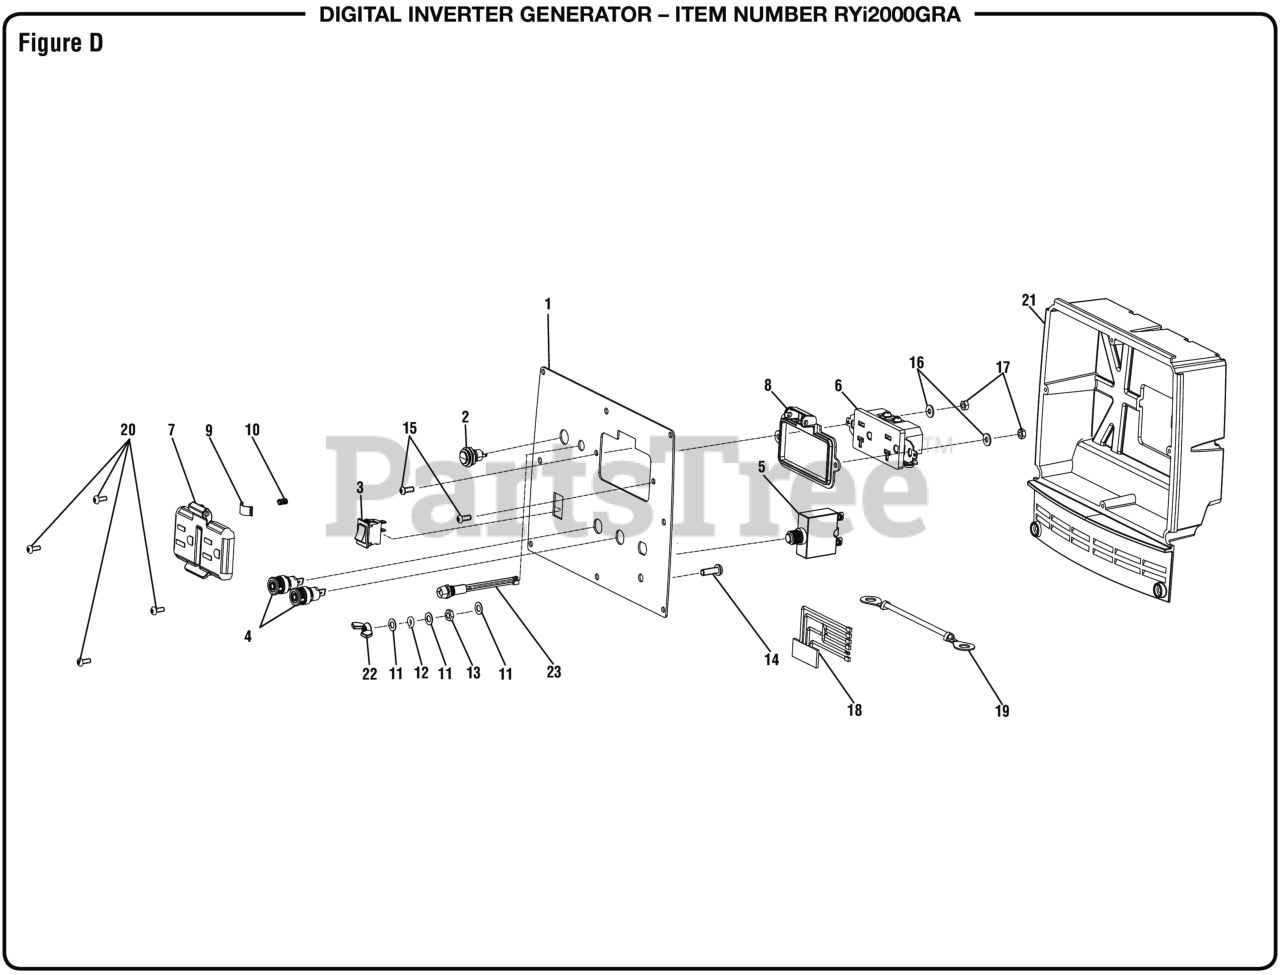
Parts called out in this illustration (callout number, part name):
1	Front Cover
2	Reset Button
3	Auto Idle Switch
4	Connector (Black)
5	Circuit Breaker (20 Amp, 125 Volt)
6	120 Volt Duplex Receptacle (BM903611)
7	Receptacle Cover (Front)
8	Fixed Outlet Cover
10	Governor Damping Spring
11	Flat Washer (OD10 x ID5.3 x 0.5t)
12	Lock Washer (OD9 x ID5 x 1.3t)
13	Hex Nut (M5)
14	Screw (M5 x 16 mm, Phillips Pan Hd.)
15	Bolt (M4 x 10 mm, T15 Torx Drive Hd.)
16	Flat Washer (OD10 x 42 x 1t)
17	Flange Nut (M4)
18	Internal Wire Assembly
19	Ground Wire
20	Screw (#6-20 x 3/8 in., T15 Torx Pan Hd.)
21	Electrical Panel Housing
22	Wing Nut (M5)
23	Indicator (Red LED 3.3V-4mA)
